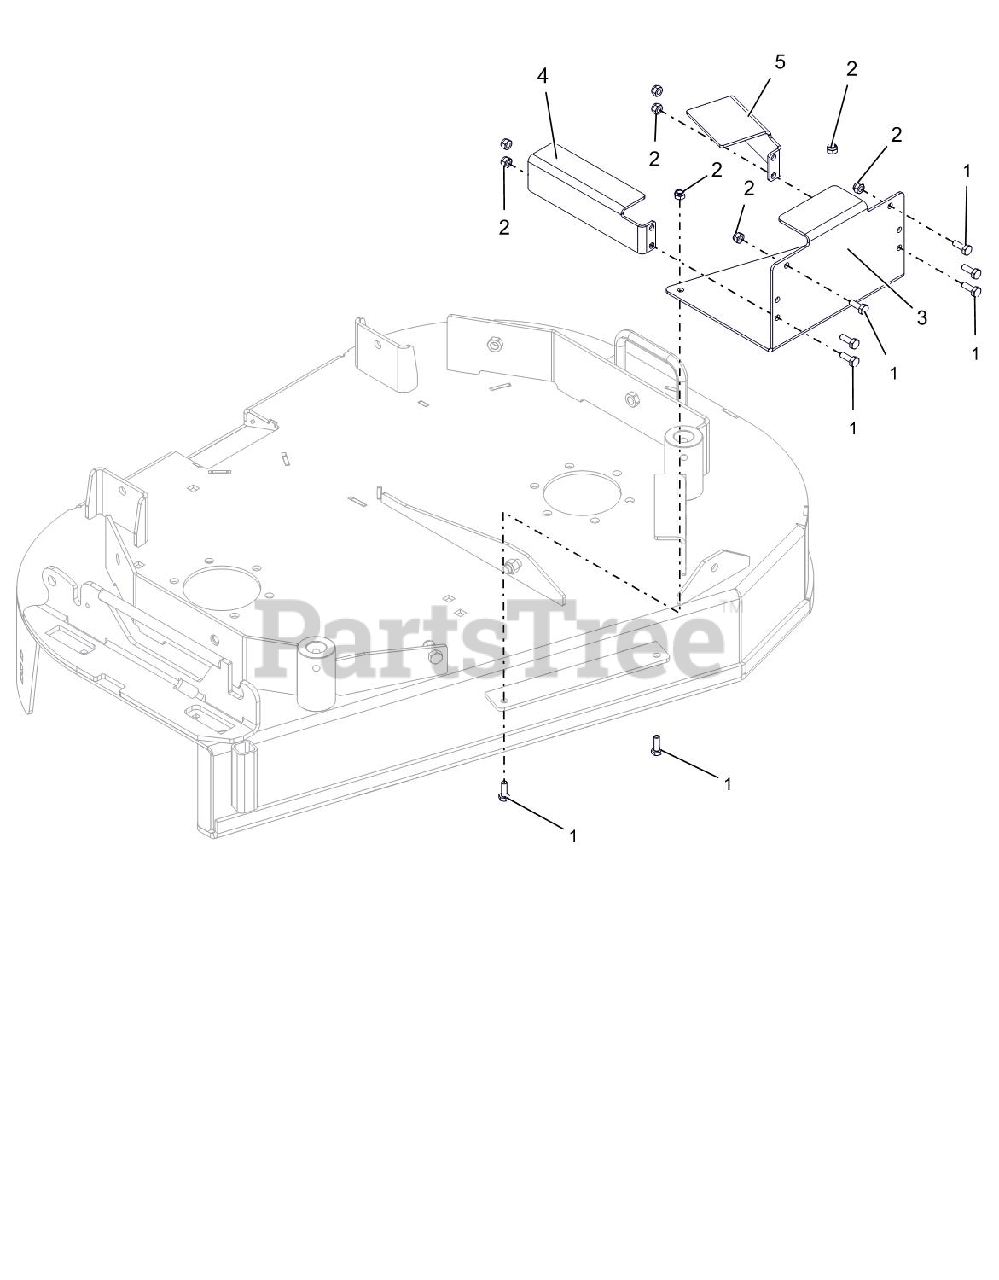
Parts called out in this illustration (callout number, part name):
1	BLT, HEX .25-20X.75 GR5 ZC120
2	NUT,NYL .25-20 G5 ZCC
3	COVER, FRONT
4	SHIELD, BELT RH
5	SHIELD, BELT LH
